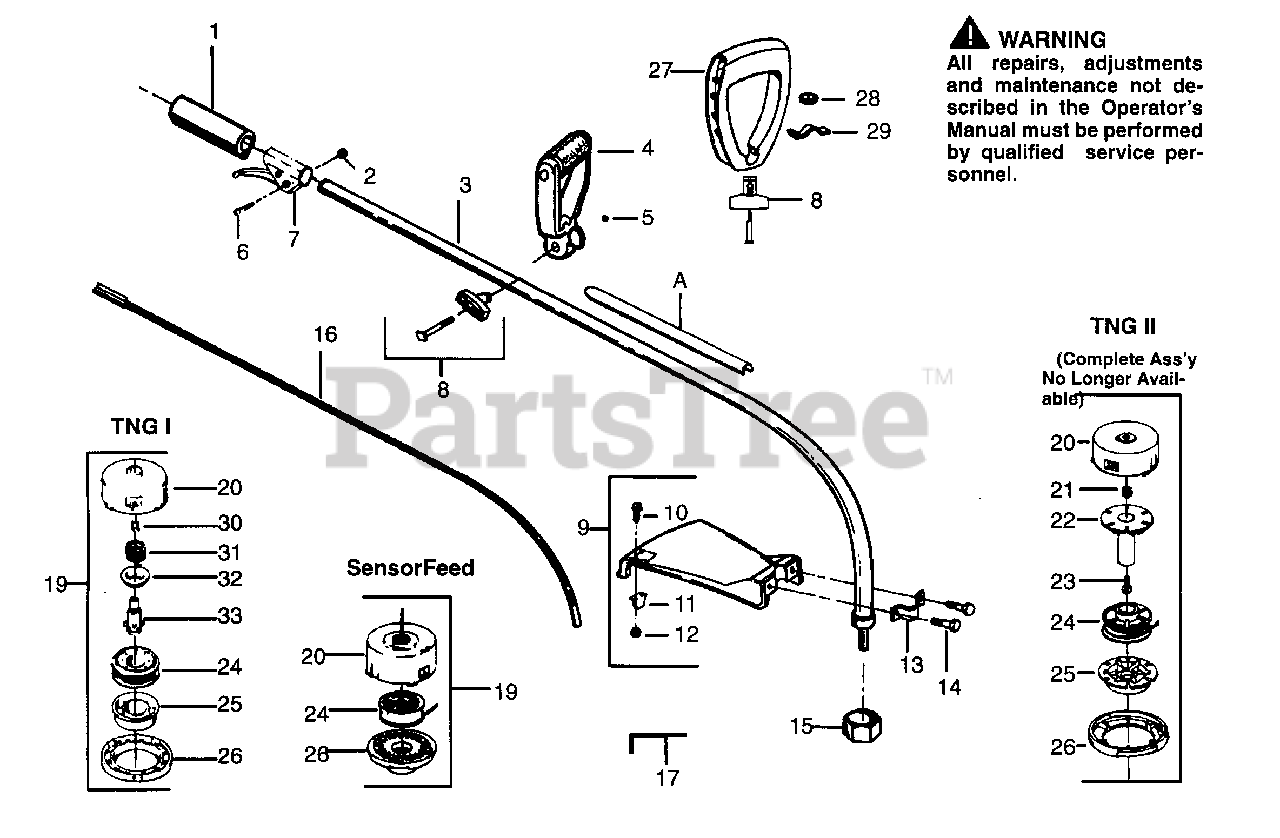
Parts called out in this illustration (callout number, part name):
3	Drive Shaft Housing
4	Handle Ass'y.
7	Throttle Housing Ass'y.
8	"T" Handle Kit
9	Shield Kit Ass'y. (Inc. 10,11,12,14)
11	Line Limiter
12	Locknut
13	Shield Bracket
15	Dust Cup
16	Drive Shaft
17	Hex Wrench (5/32)
19	SensorFeed
19	TNG I
19	TNG II
20	SensorFeed
20	TNG I
24	SensorFeed
24	TNG II
26	SensorFeed
30	Line Saver
32	Spring Cap
33	Drive Gear
A	Shaft Warning Decal
